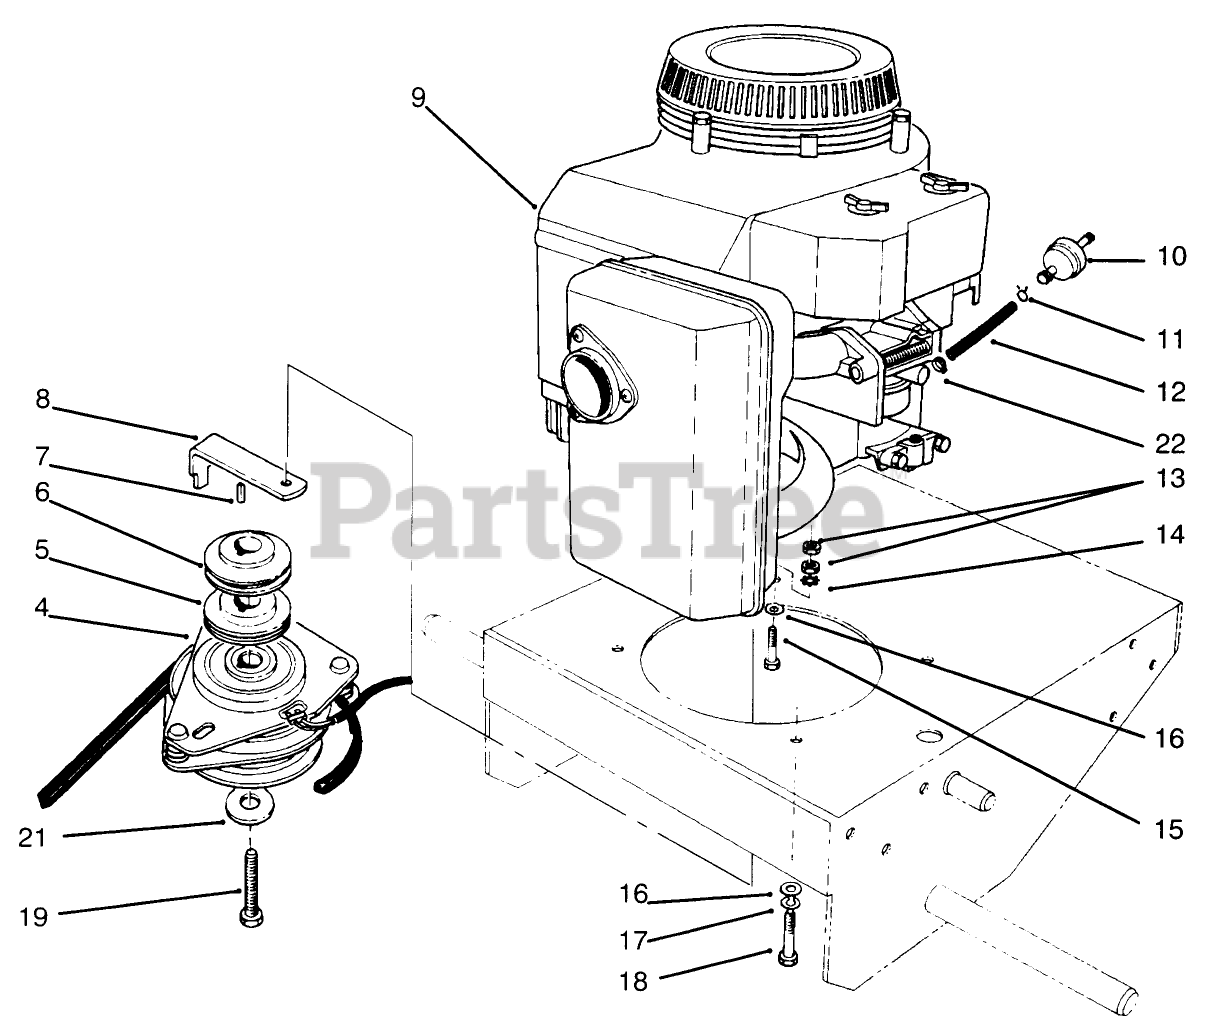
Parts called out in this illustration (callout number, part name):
5	SHEAVE-HALF, LOWER
6	SHEAVE-HALF, UPPER
7	KEY-SQUARE
9	Engine-Kawasaki Model FB460V Type DS08 Used On Serial Nos.590001-590900 Engine-Kawasaki Model FB460V Type JS08 Used On Serial Nos.590901 UP
10	FILTER-FUEL
11	CLAMP-HOSE
13	NUT-JAM
14	WASHER-LOCK
15	SCREW
16	WASHER-PLAIN
17	WASHER-LOCK
19	SCREW-CLUTCH
22	CLAMP-WORM
